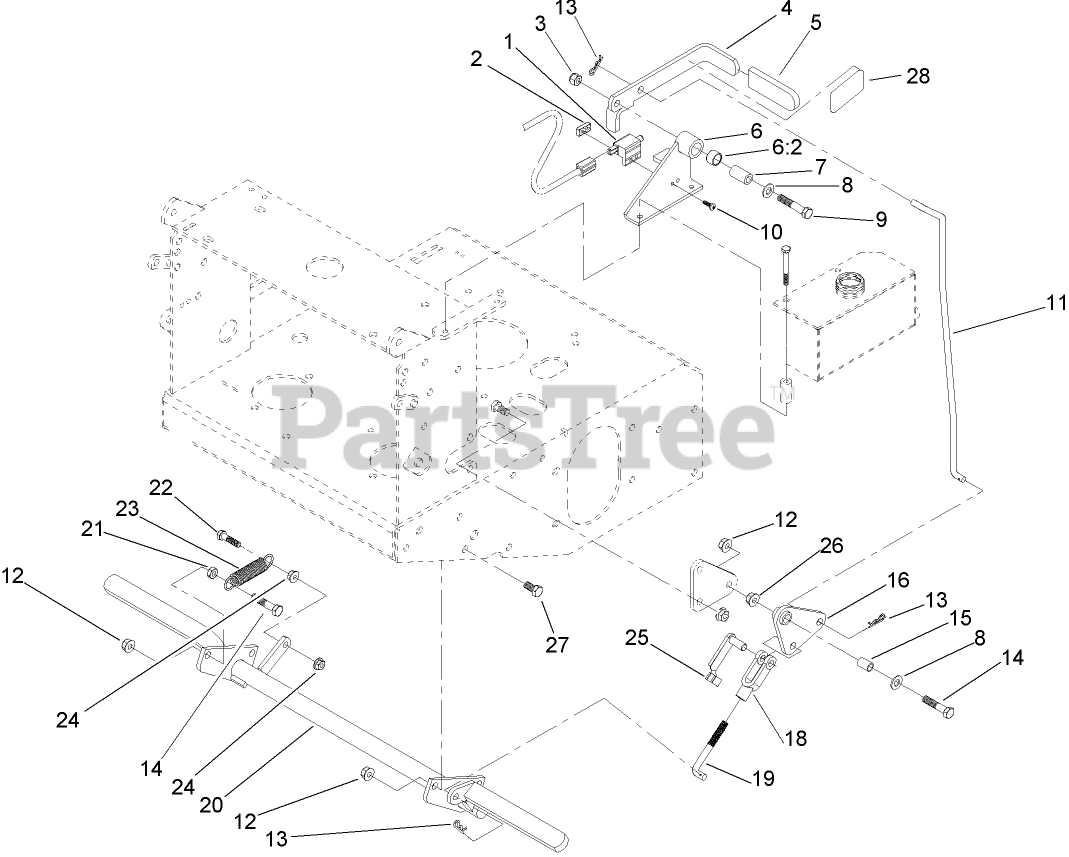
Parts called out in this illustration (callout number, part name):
1	SWITCH-OPEN, NORMALLY
2	PLATE-TAPPED
3	NUT-LOCK, NI
4	Lever-Parkbrake
5	GRIP-LEVER
6	Bracket ASM
6:2	SLEEVE-BUSHING
7	Bushing-Pivot
8	WASHER-FLAT
9	SCREW-HH
10	SCREW-PPH
11	Linkage-Upper
12	NUT-HHF, WHIZ
13	PIN-COTTER
14	SCREW-HH
15	Bushing-Plastic
16	Bellcrank ASM
18	YOKE-LINKAGE, BRAKE
19	Linkage-Lower
20	BRAKE
21	NUT-JAM
22	SCREW-HH
23	SPRING-IDLER
24	NUT-HF
25	Pin-Spring, Clevis
26	NUT-HF
27	SCREW-HH
28	DECAL-BRAKE, PARK
